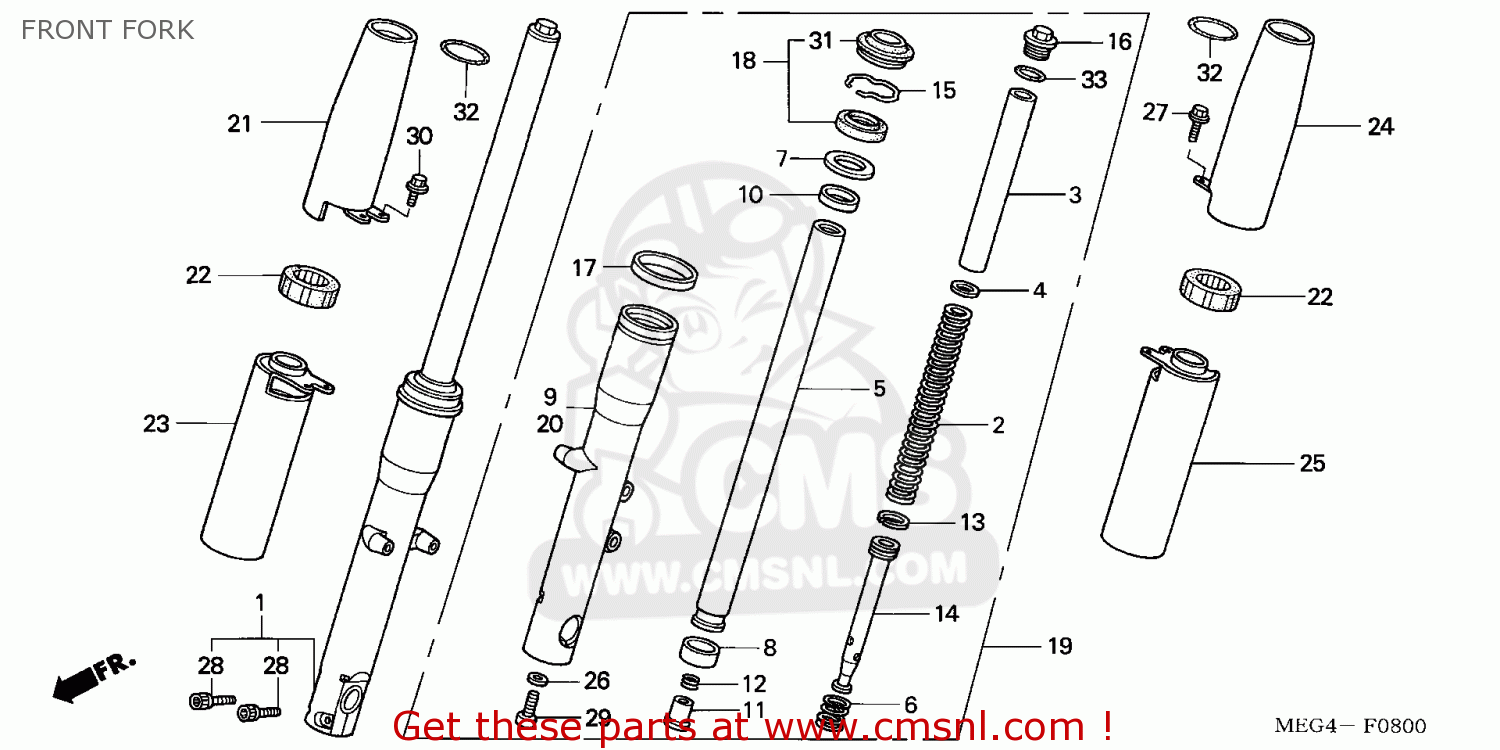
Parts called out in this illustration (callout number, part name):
1	FORK ASSY,R FR
2	SPRING,FR CUSHION
3	SPACER,SPRING
4	WASHER
5	PIPE COMP,FR FORK
6	SPRING,FR REBOUND
7	WASHER
8	BUSH,SLIDER
9	CASE,RH BOT
10	BUSH,GUIDE
11	PIECE,OIL LOCK
12	SPRING,OIL LOCK
13	RING,PISTON
14	PIPE SEAT
15	RING,SNAP
16	BOLT,FR FORK
17	GUIDE,COVER
18	SEAL SET,FR FORK
19	FORK ASSY,L FR
20	CASE,LH BOT
21	COVER COMP,R FR F
22	MOUNT,FR FORK COV
23	COVER COMP, R FR
24	COVER COMP,L FR F
25	COVER COMP,L FR F
26	WASHER,OIL BOLT
27	BOLT, FLANGE 8X1
28	SOCKET BOLT,8X35
29	BOLT,SOCKET,10X25
30	BOLT,FLANGE SH 6X
31	SEAL,DUST
32	O-RING,39.5X5
33	O-RING,31.7X3.5
